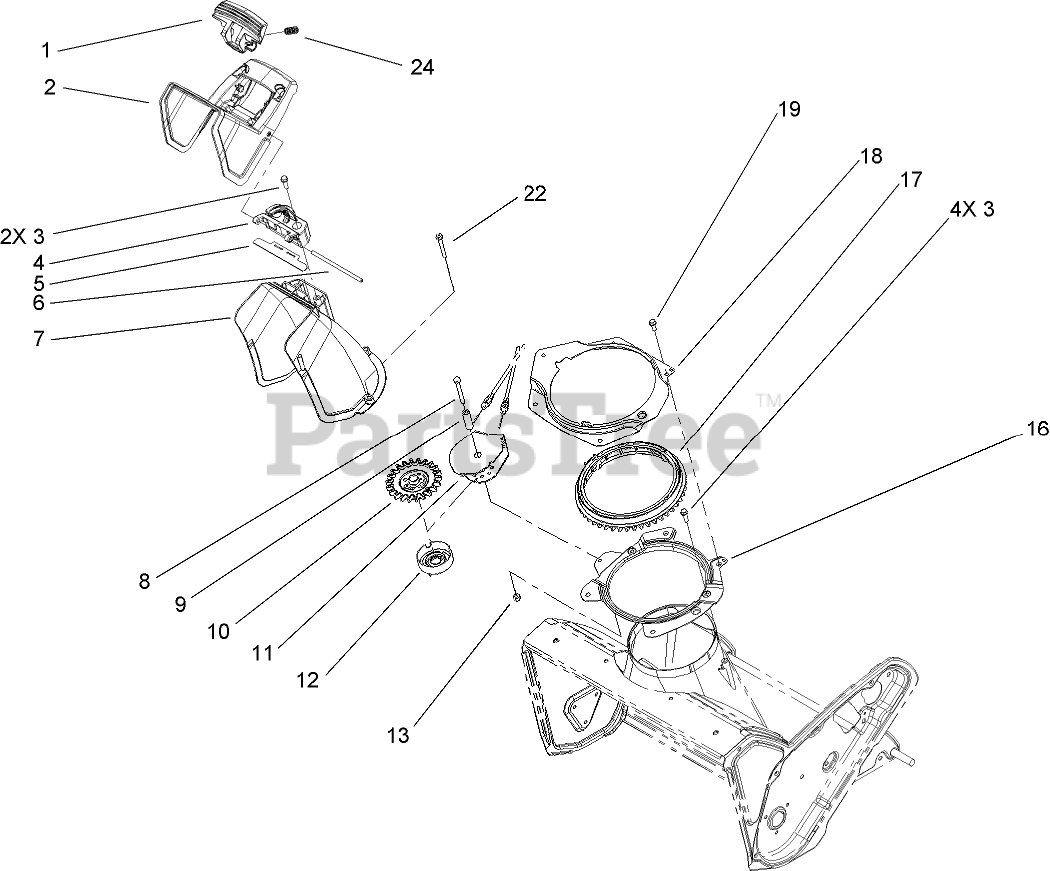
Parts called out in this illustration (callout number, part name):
1	TRIGGER-DEFLECTOR
2	DEFLECTOR
3	SCREW-HWH
4	HINGE-RATCHET, DEFLECTOR
5	SEAL-DEFLECTOR
6	PIN-HINGE, DEFLECTOR
8	SCREW-HH
9	SPACER-SLEEVE, PINION
10	PINION-GEAR
11	BRACKET-PINION
12	RETAINER-CABLE
13	NUT-LOCK, NI
16	RING-SUPPORT, CHUTE
17	RING-CHUTE, GEAR
18	RETAINER-RING, CHUTE
19	SCREW-HWH
22	SCREW-PLASTITE
24	SPRING-COMPRESSION
